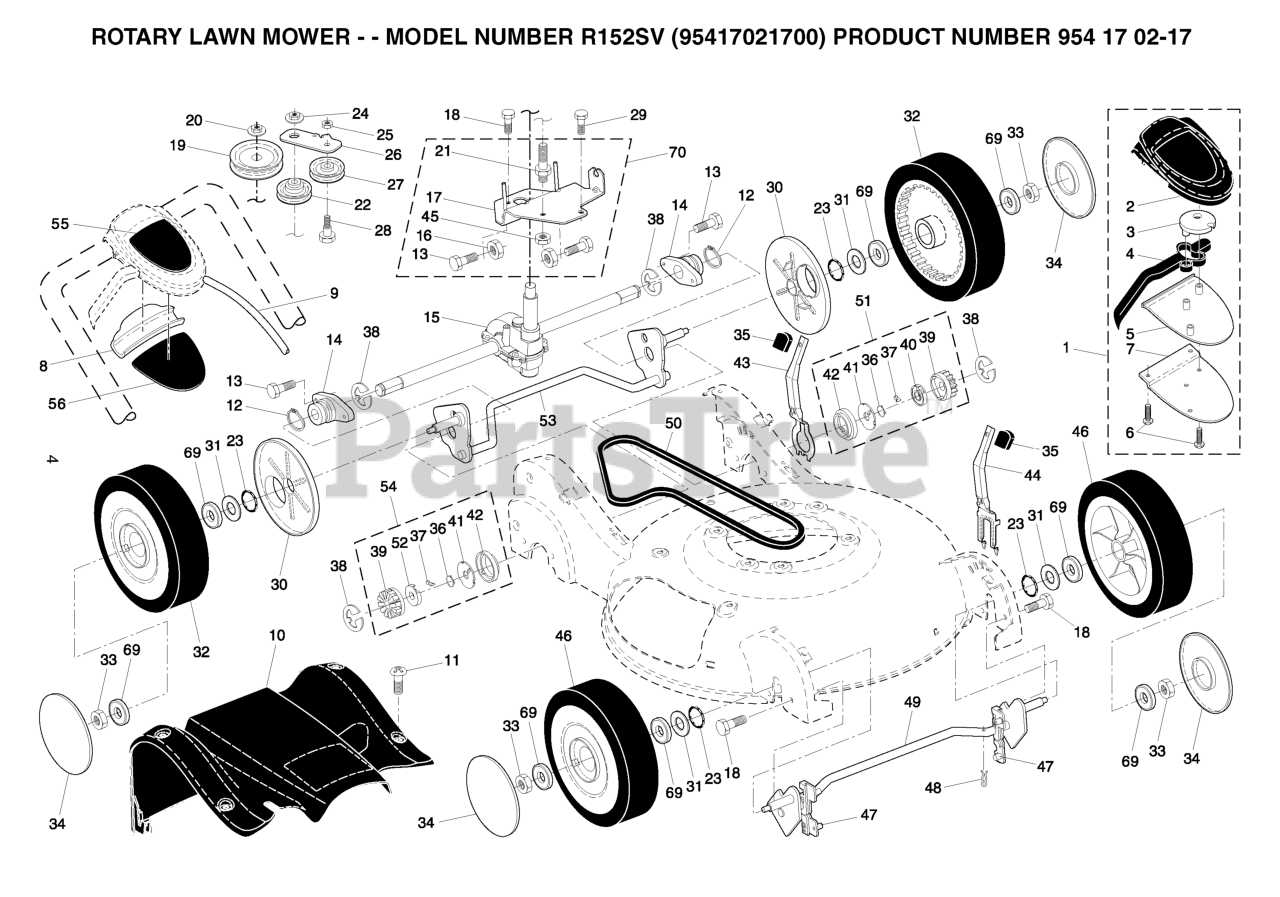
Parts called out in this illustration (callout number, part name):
1	EZ WALK CONTROL
2	COVER, DRIVE CONTROL, TOP
3	PULLEY.CAM.DRIVE.CONTROL.HV
4	LEVER, DRIVE CONTROL
5	COVER, DRIVE CONTROL BOTTOM
6	SCREW, PHILLIPS HEAD 10 X 5/8
7	BRACKET, DRIVE CONTROL
8	EZ WALK SNAP COVER PLATE
9	CABLE, DRIVE CONTROL
10	COVER ASM. DRIVE
11	SCREW
12	RETAINING RING (2 2)(3 2)
13	RP SCREW
14	BEARING.SUPPORT.ASSEM
15	TRANSMISSION.21.HI-VAC.EZ
16	NUT
17	BRACKET TRANSMISSION
19	RP PULLEY DRIVE
20	FLANGED LOCKNUT 3/8-16 ZINC
21	BOLT, IDLER
22	PULLEY ASSY
23	O-RING
24	NUT
25	NUT.CENTERLOCK.5/16-
26	BRACKET
27	IDLER PULLEY
28	SHOULDER BOLT
29	SCREW 14-20 X 5/8
30	DUST COVER, WHEEL
31	WASHER.FLAT.1/2
32	WHEEL.9X2.25.PR.JUNG.BLK
33	HEX FLANGE LOCKNT
34	RB HUBCAP.3-SPOKE.SILVER
35	KNOB.SELECTOR.SPRG.H-GRY (2 2)
36	SPRING, TORSION
37	PAWL.DRIVE.21.EZ-WALK
38	E-RING 7/16 RE
39	GEAR, PINION
40	RETAINER.DRIVE.21.EZ-WALK.LT
41	DISC.DRIVE.21.EZ-WALK
42	SEAL.PINION
43	LEVER, SELECTOR, HEIGHT, REAR
44	LEVER, SELECTOR, HEIGHT, FRONT
45	NUT.LOCK.5/16-18
46	WHEEL.9X2.25.LP.JUNG.BLACK
47	BUSHING.FRONT.TORQUE.SHAFT
48	SPRING RETAINER
49	TORQUE SHAFT ASSY
50	BELT.DRIVE.EZ.WALK.HI-VAC
51	PINION ASSY, LH
52	RETAINER, DRIVE, RH
53	REAR AXLE ASSY.
54	PINION ASSY, RH
55	DECAL, DRIVE
69	BEARING.8".WHEEL
